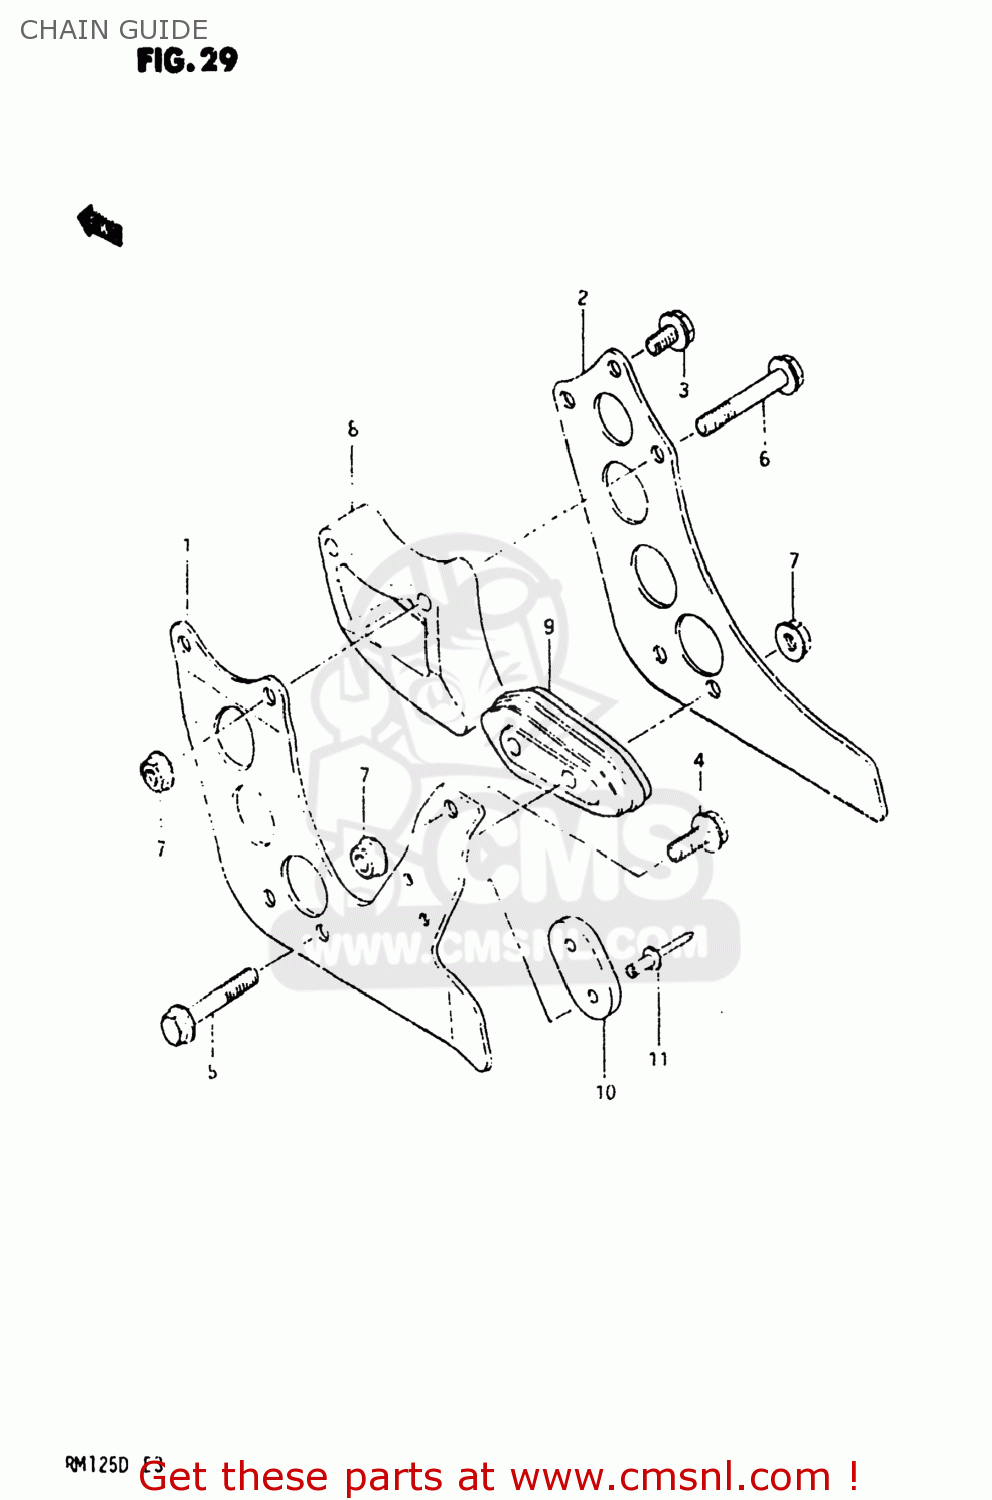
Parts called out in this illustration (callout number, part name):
1	PLATE,CHAIN GUIDE,OUTER
2	PLATE,GUIDE CHAIN
3	BOLT
4	BOLT
5	BOLT
6	BOLT,UNDER
7	NUT
8	DEFENSE,CHAIN GUIDE UPR
9	DEFENSE,CHAIN GUIDE
10	PAD,DRIVE CHAIN GUIDE
11	RIVET
